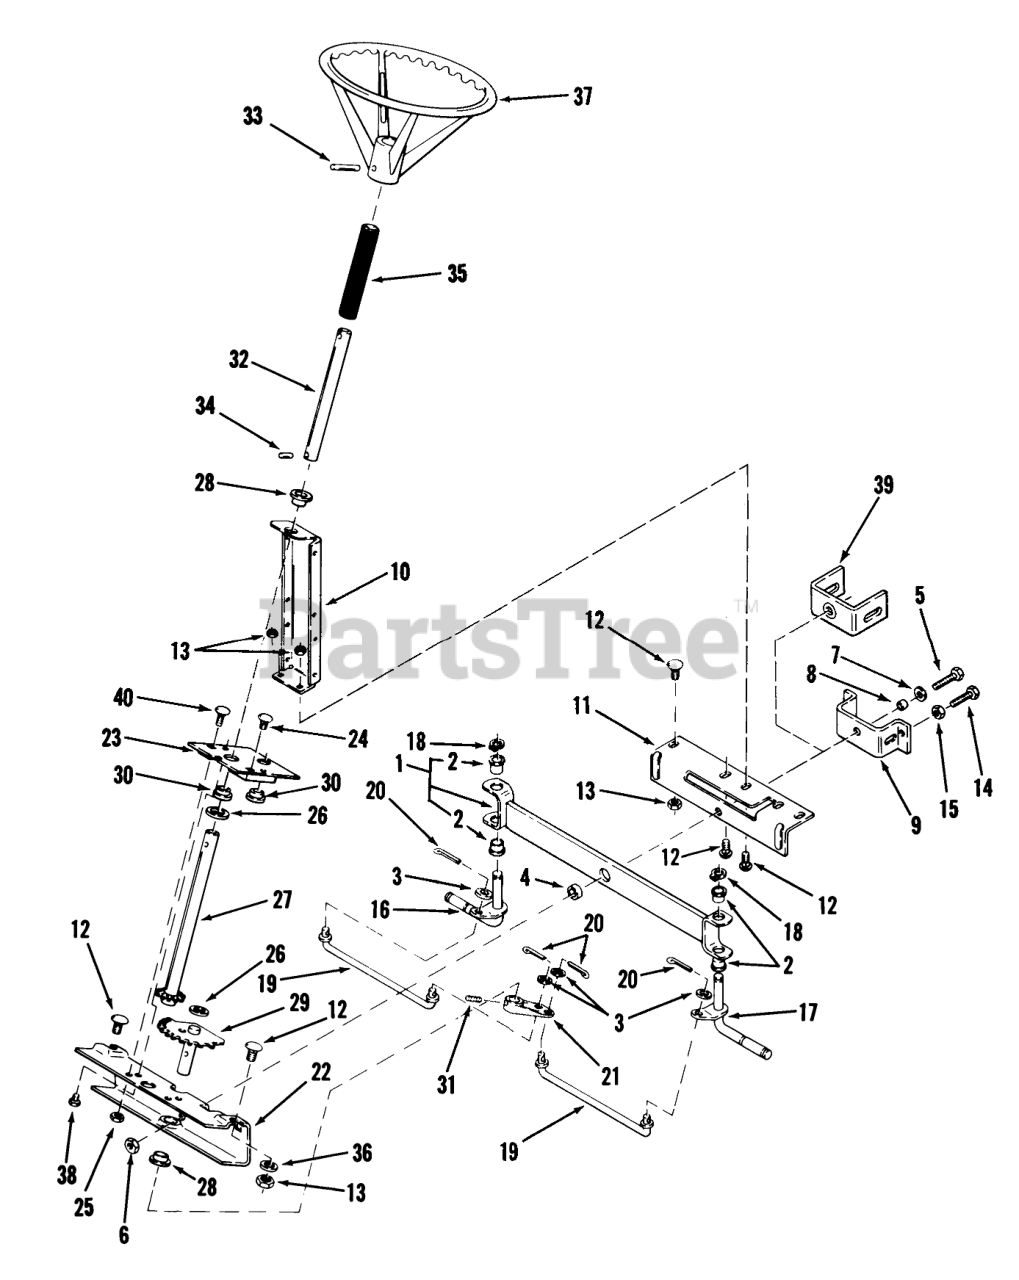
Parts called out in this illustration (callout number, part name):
1	ASSY-FRNT AXLE/BRG
2	BUSHING
17	ASSY-SPINDLE LH *R
21	ARM-STEERING
28	BEARING
29	ASSY-STEERING SEC *R (NS)
30	BUSHING
31	PIN-ROLL, SPIROL
34	SPIROL PIN
38	Bolt
